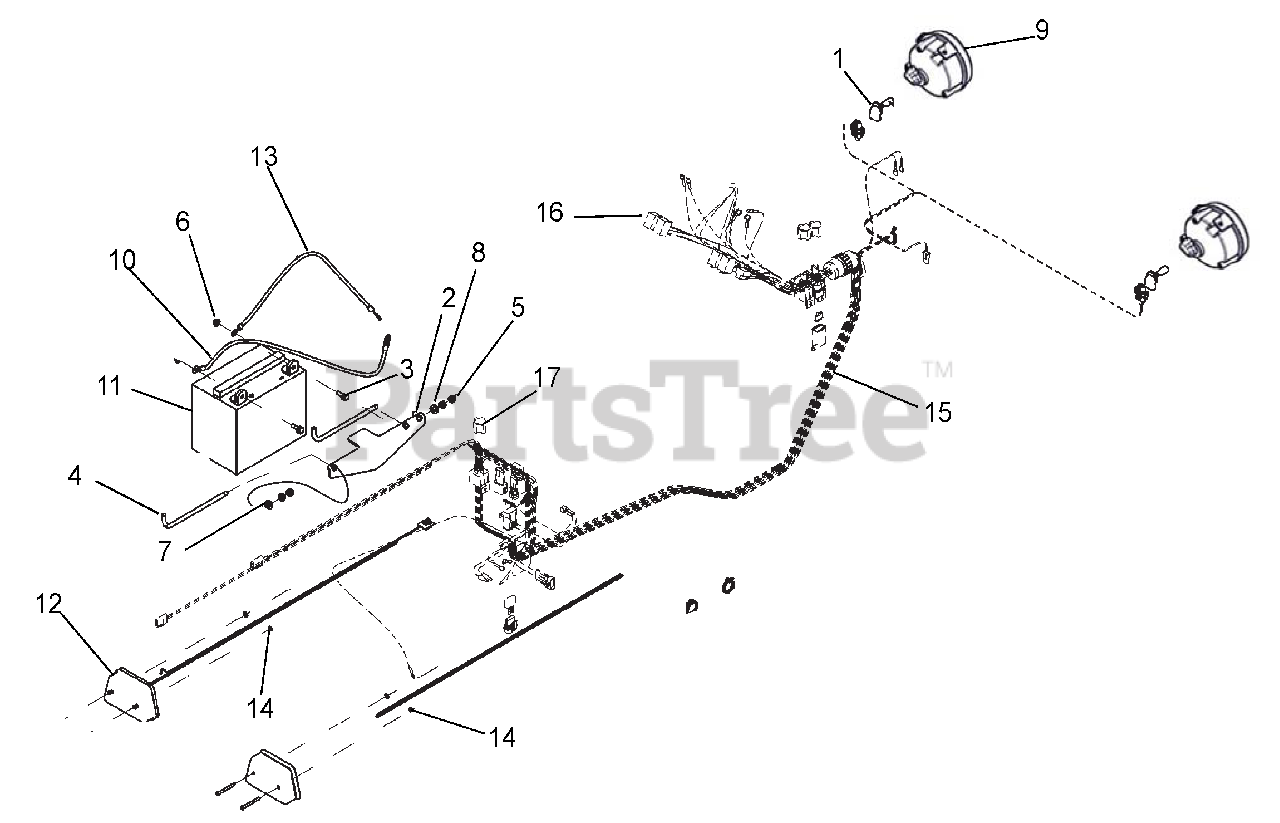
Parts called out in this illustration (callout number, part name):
2	HOLDOWN, BATTERY ST
3	SCR-HEX-FLNG .25-20 X .625 G2
4	SP HOOK 5/16-18X9X3 THREAD
5	@NUT-HEX .31-18 YWZC
6	@NUT-LK-TOP-FLG .25-20 YWZC
7	@WSHR-FL-STL.312X.734X.065 YWZ
8	@WSHR-LK .31X.078 REG YWZC
9	HEADLIGHT, ROUND
10	BATTERY CABLE POSITIVE 15 INCH
11	BATTERY
12	TAIL LIGHT, LED
13	20" 6GA NEGATIVE BLACK CABLE
14	PUSH RETAINERS 4 NON-THRD SHFT
15	HARNESS, MAIN
16	HARNESS, SUB DASH
17	RELAY, ISO MINI ELEC.
